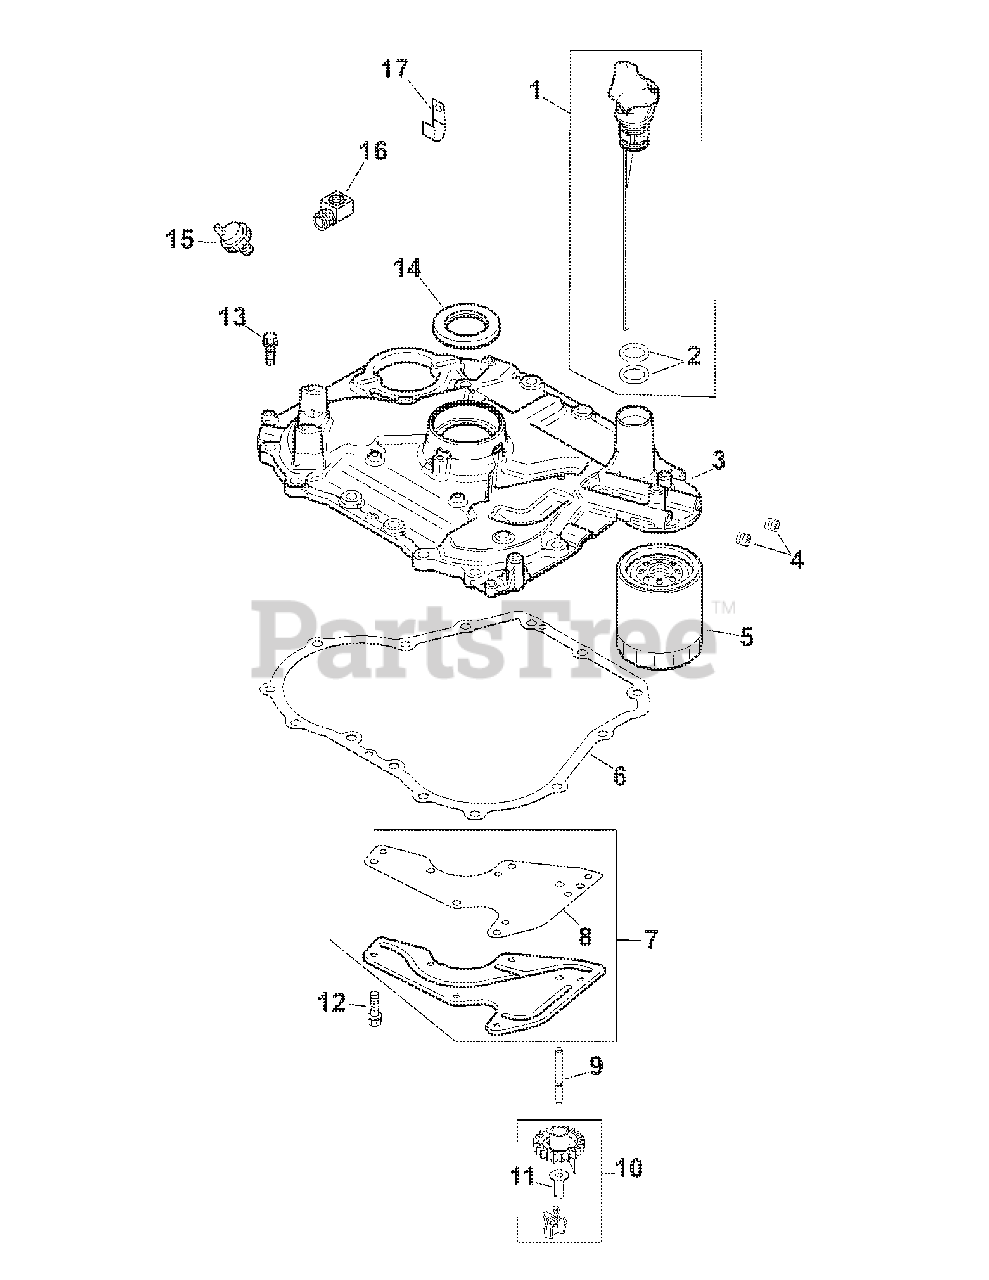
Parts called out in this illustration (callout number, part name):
1	Dipstick Assembly Kit
2	Dipstick O-Ring
3	Closure Plate Assembly
5	Oil Filter
6	Closure Plate Gasket
7	Oil Passage Cover Kit
8	Oil Passage Gasket
9	Governor Gear Shaft
10	Gear & Weight Assembly
11	Governor Regulating Pin
12	Hex Flange Screw (M5 x .8 x 13)
13	Hex Flange Screw (M8 x 1.25 x 30)
14	Oil Seal
15	Pressure Switch
16	1/8" N.P.T.F. Elbow
